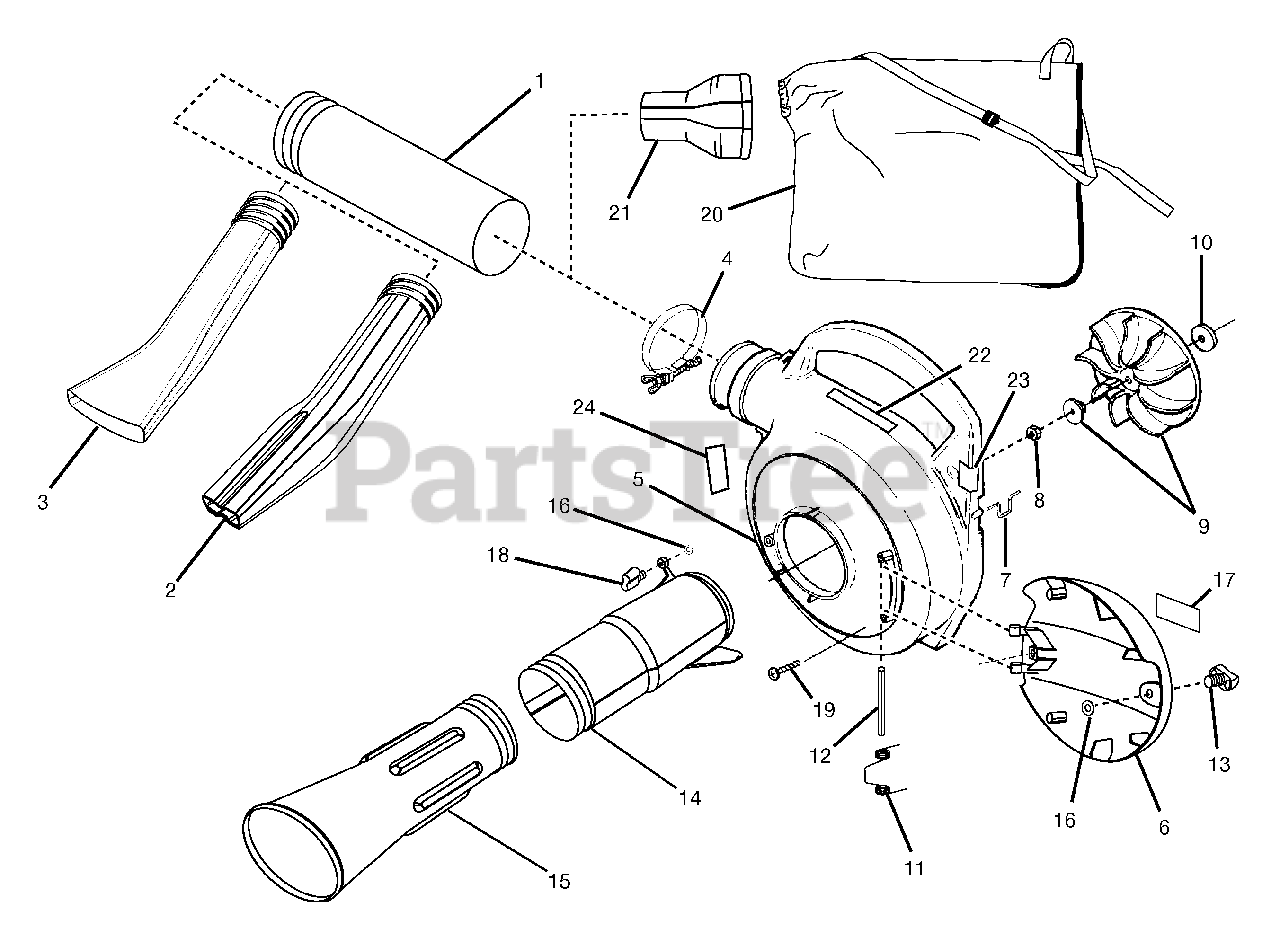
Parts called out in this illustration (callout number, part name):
1	UPPER TUBE
2	SWEEPER NOZZLE
3	LOWER NOZZLE
4	CLAMP WITH FASTENERS
5	OUTER VOLUTE HOUSING
7	WIRE LOOP
8	HEX NUT (3/8-24)
9	BLOw ER FAN KIT
10	FLAT WASHER
11	DOOR HINGE SPRING
12	DOOR HINGE SHAFT
13	BLOw ER KNOB
14	UPPER VACUME TUBE
15	LOw ER VACUME TUBE
17	DOOR VAC ATTACK DECAL
18	BLOWER KNOB
19	SCREW (10 x 1/2 in. TORx TRUSS HD.)
20	LEAF BAG
21	VACUUM BAG TUBE
22	WARNING DECAL
23	OUTER VOLUTE DECAL
24	FAN INTAKE DECAL
